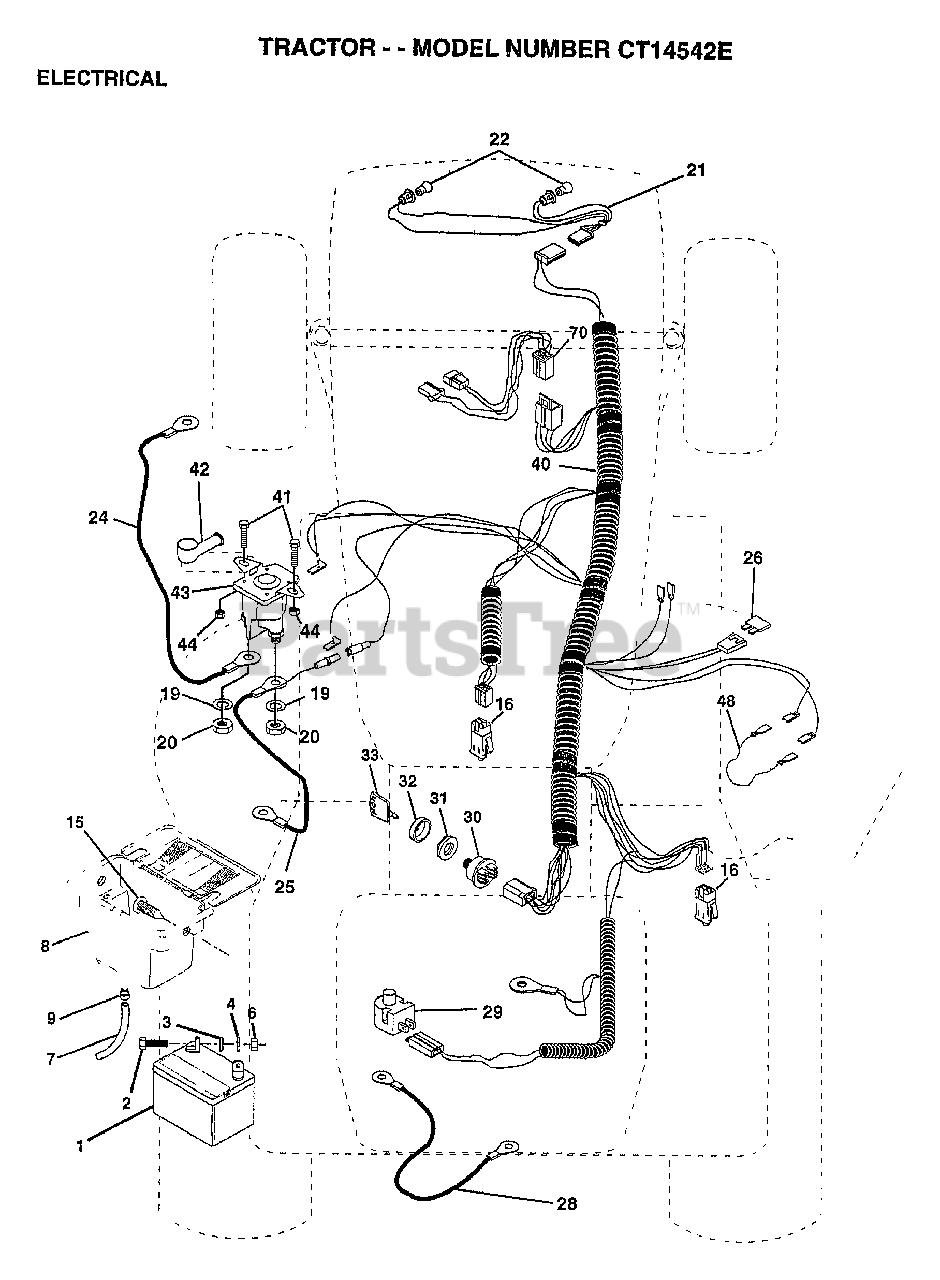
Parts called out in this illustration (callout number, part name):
2	BOLT LT
3	WASHER
4	LOCKWASHER
7	TUBE T
8	"CASE,BATTERY.MECH"
9	HOSE CLAMP T
15	FASTNER.SNAP-IN
16	SWITCH INTERLOCK
20	NUT
21	"HARNESS,LIGHT SOC"
22	HEADLAMP BULB
24	CABLE.BTRY.6GA.RD
25	CABLE.BTRY.6GA.38
26	FUSE HYT
28	CABLE T
29	SWITCH SEAT
30	SWITCH IGN 4POS
31	NUT IGNITION
32	COVER KEY SWITCH
33	KEY
40	HARNESS IGNITION
41	BOLT HXHD FIN
44	NUT HXKEP 1/4X20
48	ADAPTER AMMETER
70	HARNESS.ENG.DUAL
